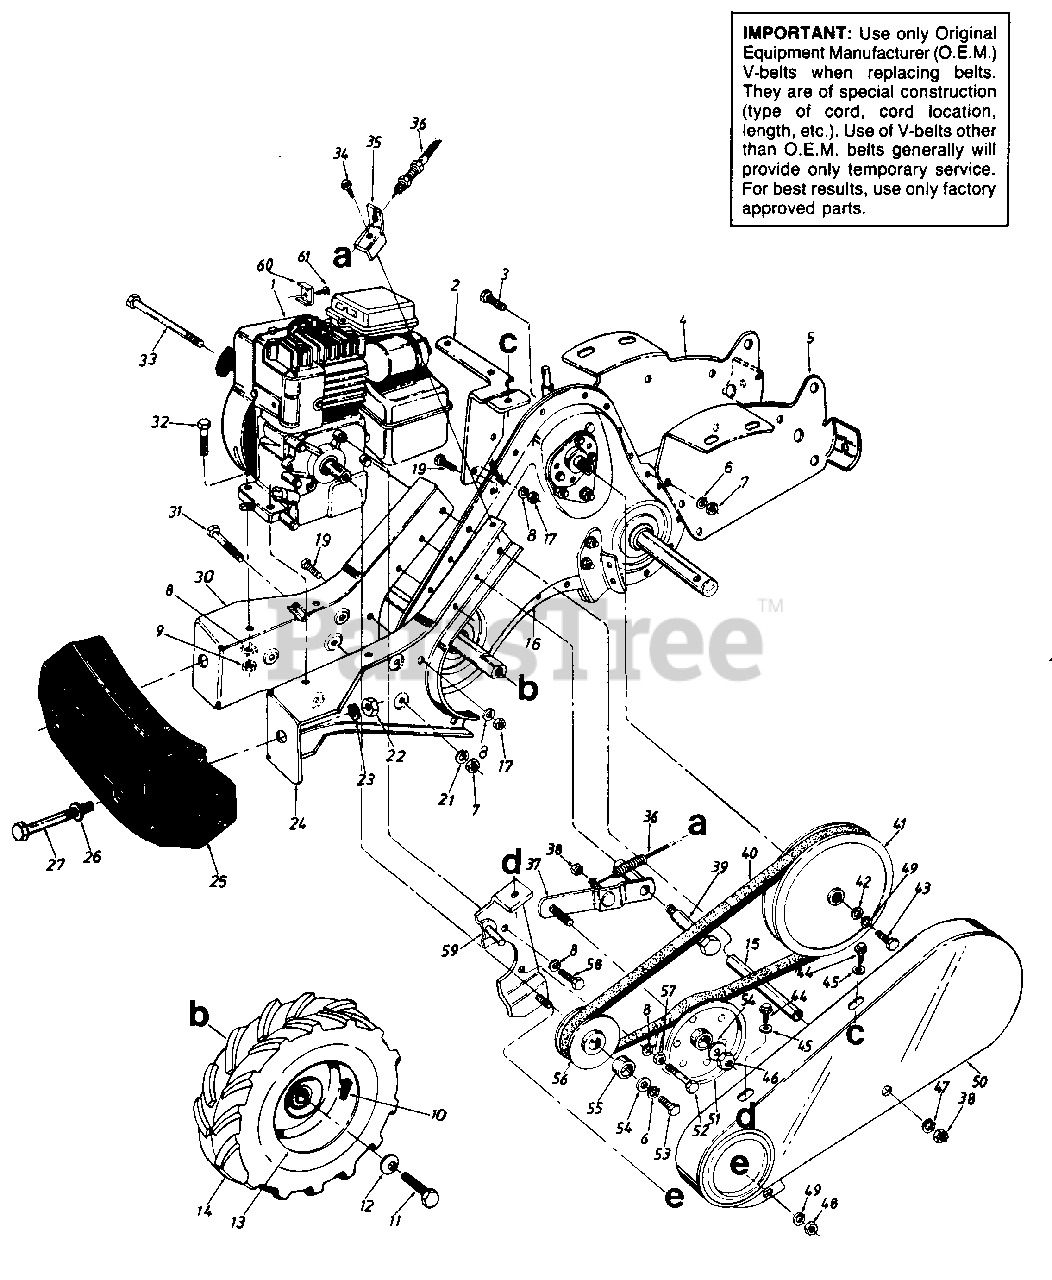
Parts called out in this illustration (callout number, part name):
1	Engine
7	Hex Nut 3/8-16 Thd.
8	L-Wash. 5/16" I.D.
9	Hex Nut 5/16-18" Thd.
10	Air Valve
11	Hex Bolt 5/16-24 x .62" Lg.
12	Bell-Wash. .345" I.D. x .88"
13	Wheel Rim Ass'y. Only
14	L.H. Wheel Ass'y. Comp.
16	Transmission Comp.
17	Hex Nut 5/16-18 Thd.
19	Hex Bolt 5/16-18 x .75" Lg.
21	L-Wash. 3/8" I.D. H.D.
22	Hex Nut 1/2-13 Thd.
23	L-Wash. 1/2" I.D.'
26	Fl-Wash. .510" I.D. x 1.0"
27	Hex Bolt 1/2-13 x 5.00" Lg.
32	Hex Bolt 5/16-18 x 1.50
33	Hex Bolt 5/16-18 x 4.75" Lg. Gr. 2
34	Hex Wash. TT-Tap Scr. 5/16-18 x .62" Lg.
35	Bracket Clutch Cable
36	Clutch Control Cable 53" Lg.
39	Shld. Bolt 500" Dia. x 2.27"
40	"V"-Belt
41	"V"-Pulley Split 5/8" I.D.
42	Fl-Wash. 1/4" I.D. x 93" O.D.
43	Hex Bolt 1/4-28 x 75" Lg.
44	Hex Wash. Hd. S-Tap Scr. 1/4-20 x .50" Lg.
45	Fl-Wash. .281" I.D. x.625"
46	Hex Cent. L-Nut 3/8 24 Thd.
47	Fl-Wash. 5/16" I.D.
48	Hex Nut 1/4-20 Thd.
49	L-Wash. 1/4" I.D.
51	Fl-Idler w/Flanges 3.75" O.D.
52	Hex Bolt 5/16-24 x 1.75"
53	Hex Bolt 3/8-24 x 1.00" Lg.
54	Fl-Wash. 3/8" I.D. x 1.00"
55	Spacer 758" I.D. x .990"
56	Engine Pulley
57	Hex Nut 5/16-24 Thd.
58	Hex Bolt 5/16-24 x .62" Lg.
61	Hex Sems Scr. #10-32 x .62"
